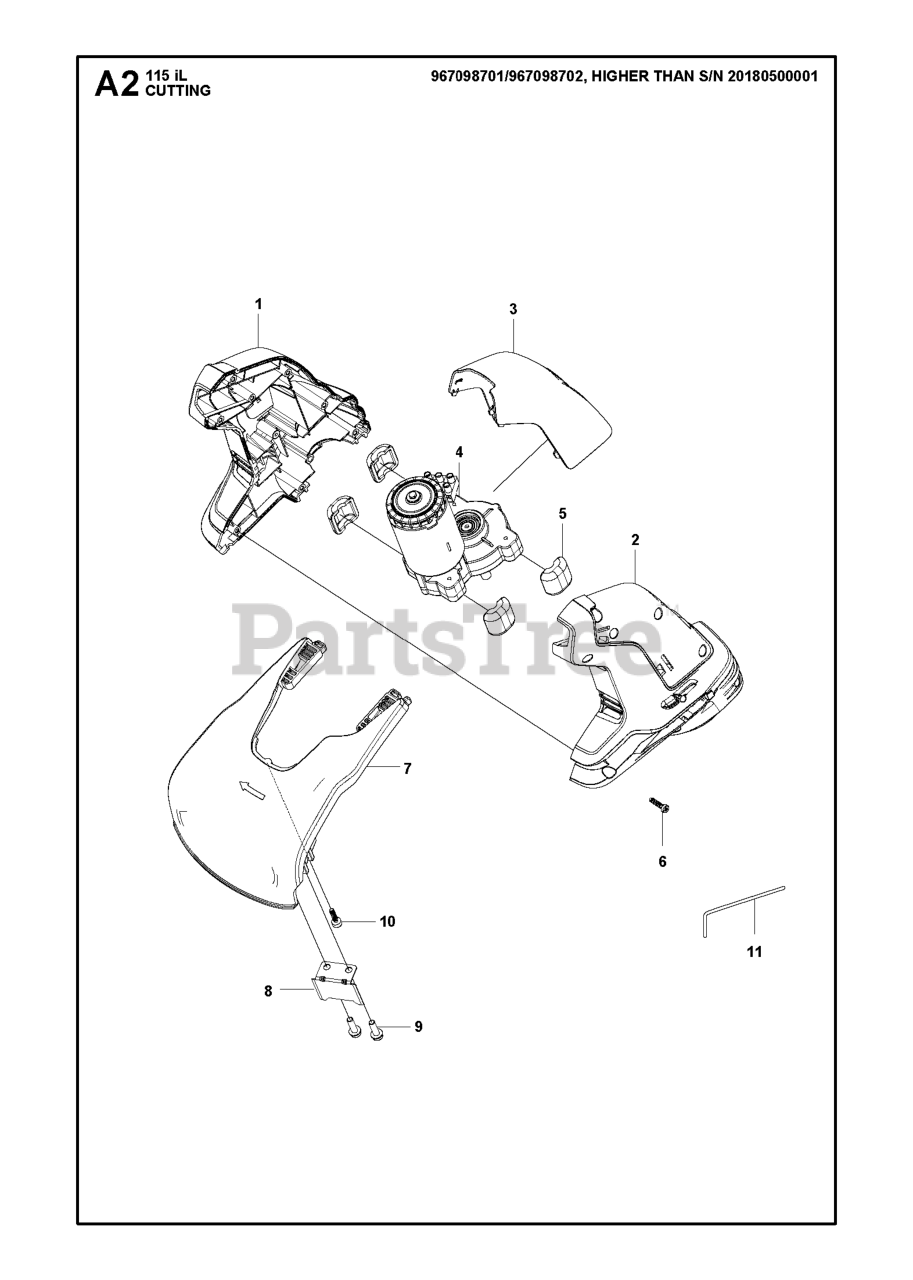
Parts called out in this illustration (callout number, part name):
1	HOUSING MOTOR HOUSING L 36V
2	HOUSING MOTOR HOUSING R 36V
3	COVER MOTOR HOUSING
4	GEARBOX ASSY 115IL TRIMMER
6	SCREW ST4X16
7	GUARD FOR CUTTING HEAD 36V
8	BLADE LINE CUTTER
10	SCREW ST4*16
